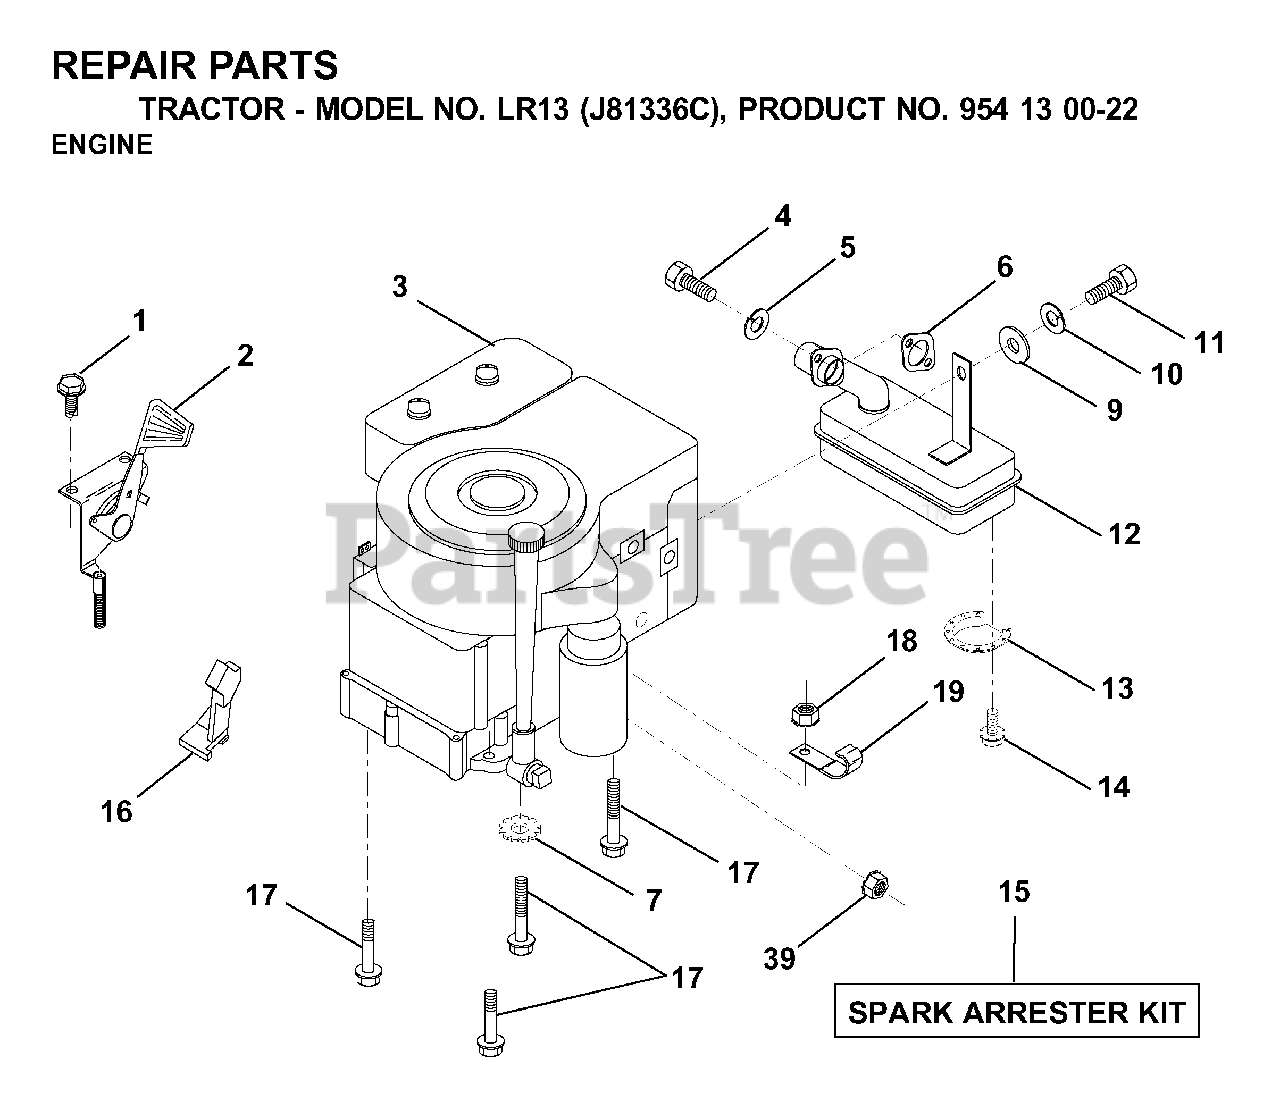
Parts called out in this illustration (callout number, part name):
1	SCREW LT
2	THROTTLE CONTROL
4	SCREW
5	LOCKWASHER
6	REPL BY 532 27 22-93
7	LOCKWASHER
9	WASHER
10	LOCKWASHER
13	DEFL MUFFLER LTV
14	SCREW
15	ARRESTER SPARK (OPTIONAL)
16	STOP THROTTLE
17	SCREW LT
19	CLIP T
39	NUT FLANGE 1/4-20 STARTER NUT
